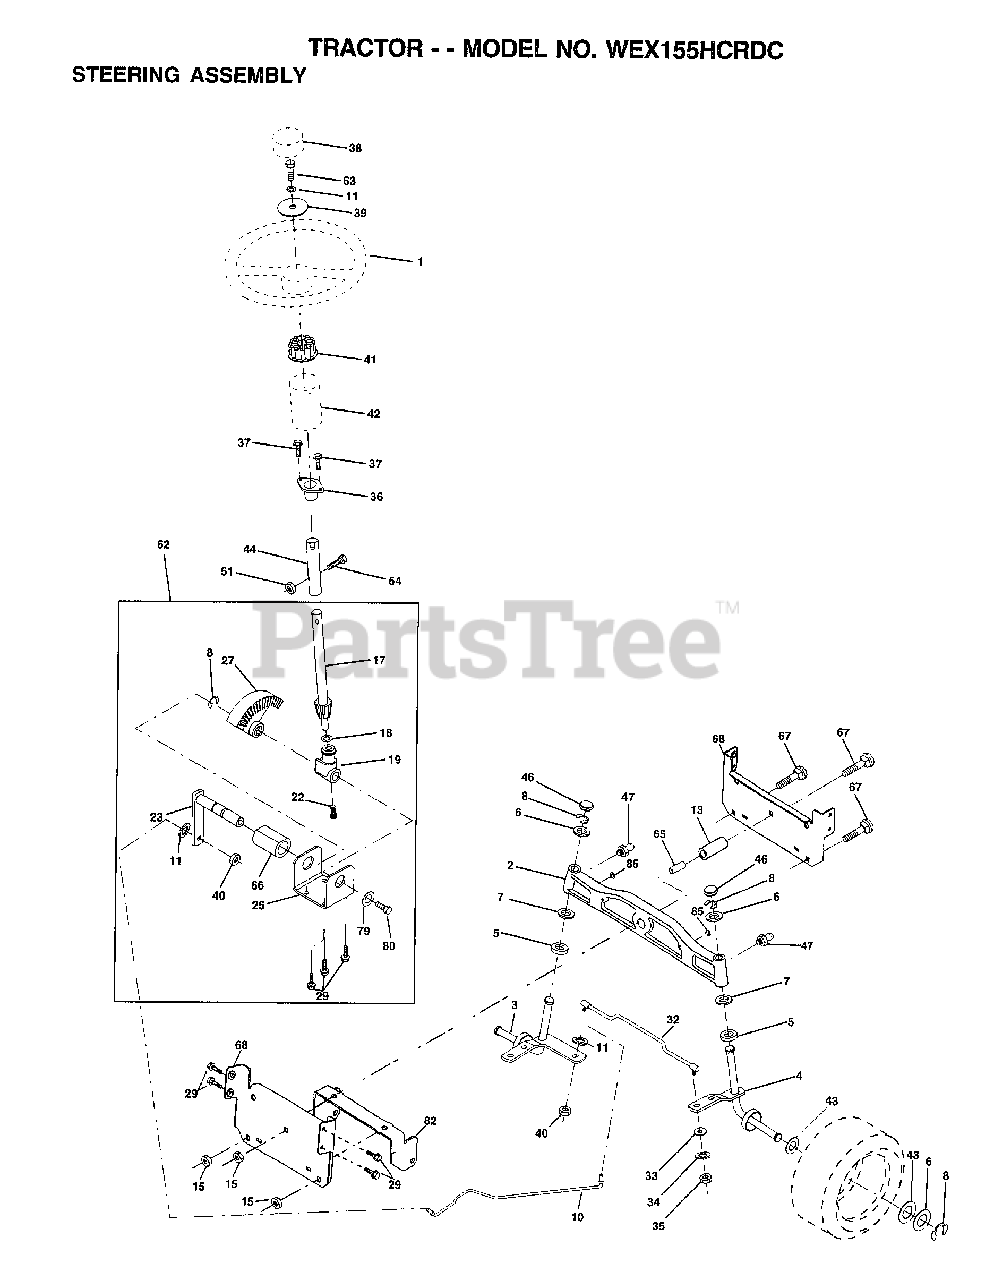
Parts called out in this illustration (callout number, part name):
1	WHEEL STR AYP BLK
2	AXLE ASM CAST IRON LT
3	SPINDLE ASM
4	SPINDLE ASM
5	WASHER .T
6	WASHER
7	WASHER
8	RING
10	LINK DRAG
11	LOCKWASHER
13	"SPACER BRCAE,AXLE"
15	NUT.HXFLG.LOCK.
17	SHAFT ASM STEERIN
18	THRUST WASHER
19	SUPPORT.SHAFT.STEER
22	SCREW.HX.WSH.HD
23	SHAFT.ASM.PITMAN
25	BRKT-STEERING
27	GEAR SECTOR
29	SCREW
32	TIE ROD
33	WASHER M
34	LOCKWASHER
35	NUT.LOCK.5/16-24
36	BUSHING.STEERING
37	"SCREW-TT,10-32 FL"
38	CAP STEER AYP
39	WASHER
40	GRIPCO NUT
41	ADAPTER LT
42	BOOT.STEERING.DASH.P/L
43	WASHER
44	EXT SHAFT STEERIN
46	CAP
47	ZERK M
51	NUT
54	BOLT
62	KIT.STEER.ASM
63	BOLT
65	SPACER BEARING
66	"BEARING-ARM,PITMA"
67	BOLT RDHD 3/8-16
68	BRACE AXLE
79	WASHER
80	BOLT.HX.NYLON3/8-16X3/
82	BRKT SUSP CHASSIS FRT
84	BRACKET CABLE CLUTCH CHASSIS
85	XMAS TREE FASTNER
